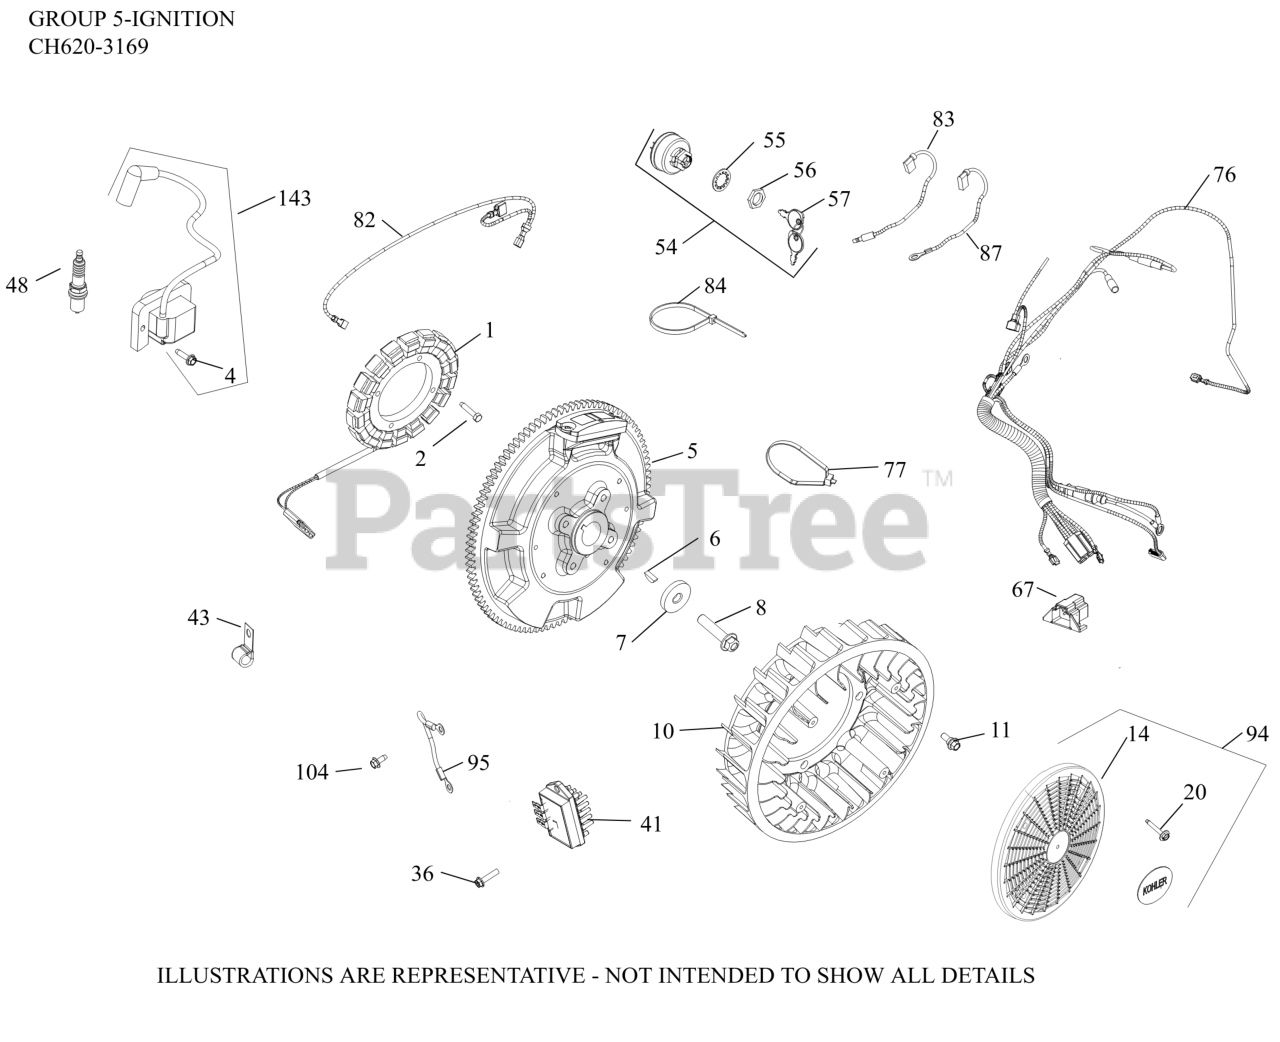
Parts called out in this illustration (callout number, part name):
1	KIT, 25 AMP STATOR ASSY.
2	SCREW, THREAD FORMING
4	SCREW, THREAD FORMING
6	KEY, 3/16" X 5/8"
7	WASHER, FLAT 13/32"
8	SCREW, FLG M10X1.5X45-USE 25 086 361-S
10	FAN-USE 24 755 253-S
11	BOLT, SHOULDER
14	SCREEN, GRASS
20	SCREW, FLG SEMS M4x.7x25
36	SCREW, HEX FLANGE HI-LO
41	REGULATOR, RECT (20-30AMP, FW W/OVP)
43	CLIP, CABLE
48	PLUG, SPARK (STD)
54	KEY ASSEMBLY SWITCH-USE 25 099 37-S
55	WASHER, INTERNAL TOOTH
56	NUT, KEY SWITCH
57	KEY, SET OF 2
67	CONNECTOR
76	HARNESS WIRING ASSEMBLY
82	LEAD, DUPLEX
83	LEAD, OIL SENTRY
87	LEAD, 20/25 AMP B+
94	KIT GRASS SCREEN
104	SCREW, THREAD FORMING
143	KIT, IGNITION MODULE
